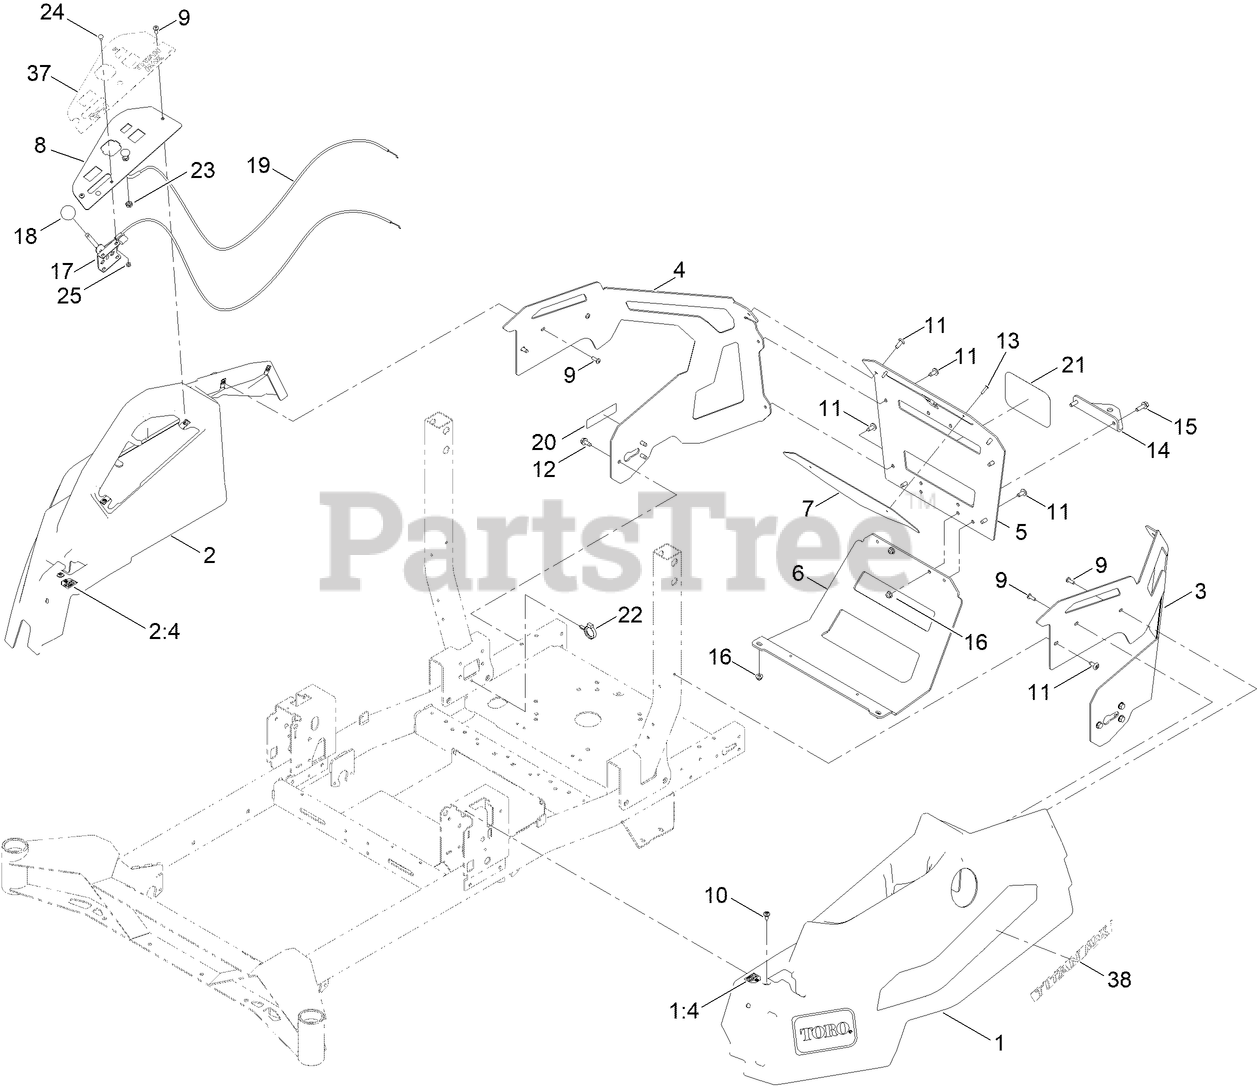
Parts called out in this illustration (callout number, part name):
1	TITAN MAX LH POD ASM
1:4	DECAL-CONTROL LEVER, LH
2	TITAN MAX RH POD ASM
2:4	DECAL-CONTROL LEVER, RH
3	GUARD-ENGINE, LH
4	GUARD-ENGINE, RH
5	GUARD-ENGINE
6	GUARD-MUFFLER
7	PLATE-BACKER
8	PANEL-CONTROL
9	SCREW-PH
10	SCREW-SHOULDER
12	SCREW-HWHTF
13	RIVET-TRIFOLD
14	BRACKET-HITCH
15	SCREW-HHF
16	NUT-HF
17	CABLE-CONTROL, THROTTLE
18	KNOB-BALL
19	CHOKE CONTROL ASM
20	DECAL-SPARK ARRESTER
21	DECAL
22	CLAMP-HOSE
23	NUT-HJ
24	BOLT-CARR
25	NUT-LOCK, NI
37	DECAL-PANEL, CONTROL
38	DECAL-TITAN MAX
